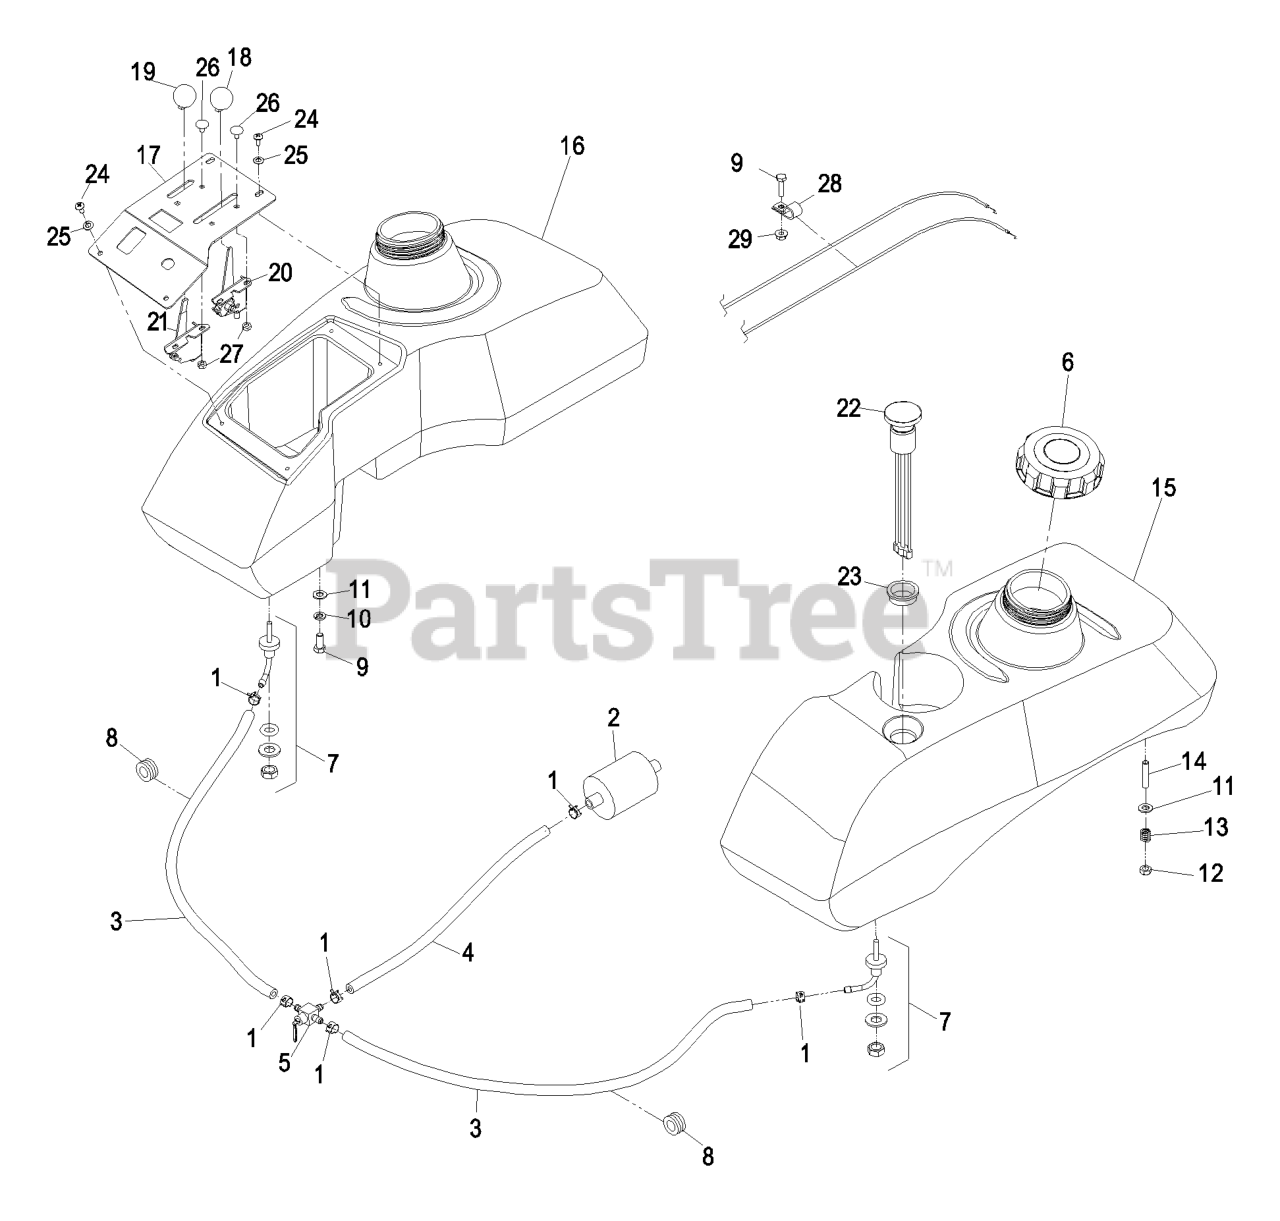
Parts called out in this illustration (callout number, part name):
2	Kohler Part No. 2405002 Fuel Filter
5	VALVE-FUEL
7	FITTING-FUEL, BULKHEAD
8	GROMMET
9	SCREW-HH
10	WASHER-LOCK
11	WASHER-PLAIN
12	NUT-LOCK, NI
13	SPRING-TANK, FUEL
14	STUD
15	KIT,FUEL TANK LH LHP
16	KIT,FUEL TANK LHP RH
18	KNOB-BALL
19	KNOB-BALL, BLACK
20	CABLE-THROTTLE
21	THROTTLE CABLE ASM
23	CONTACT ORDER SERVICES
24	SCREW-PTH
25	WASHER-SPRING
26	BOLT-CARR
27	NUT-LOCK, NI
28	CLIP-LOOM
